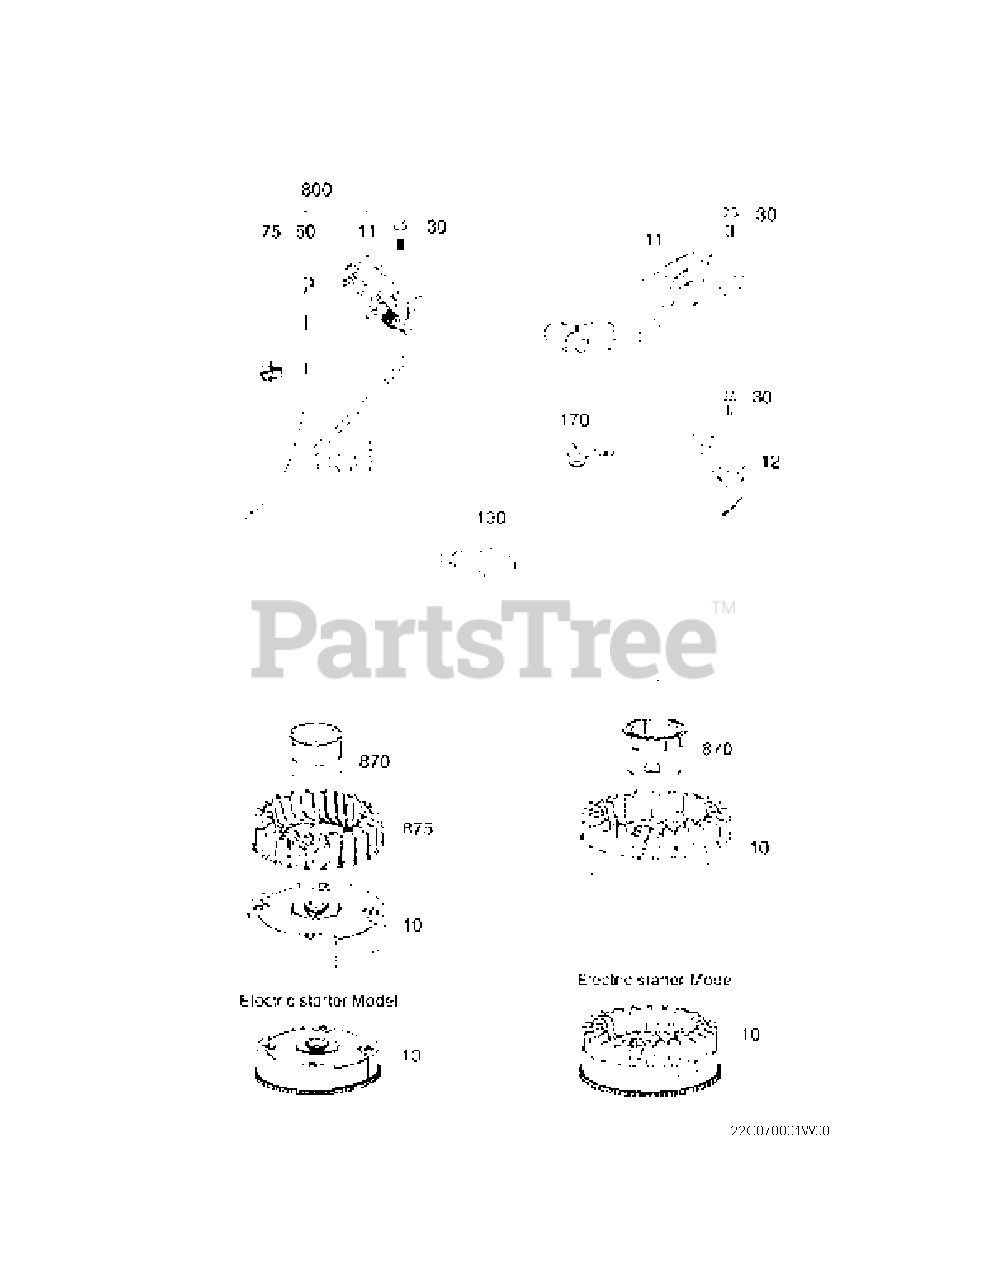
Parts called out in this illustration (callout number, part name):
10	FLYWHEEL
12	CHARGING COIL ASSEMBLY
170	CHARGING COIL CLAMP
